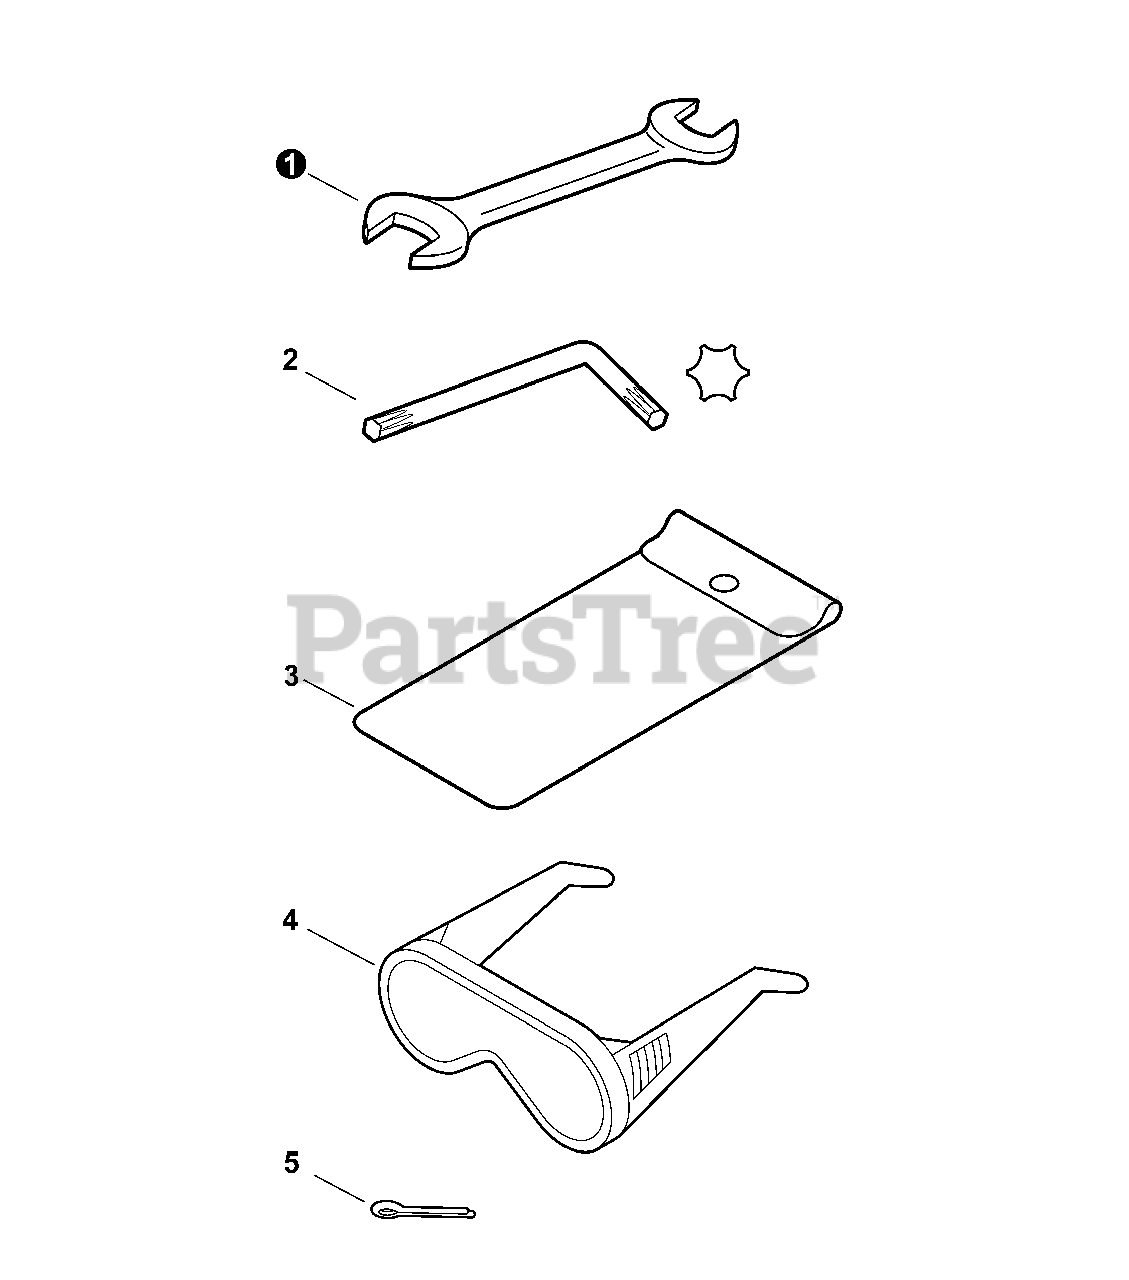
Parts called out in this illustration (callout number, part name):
1	SPANNER 8×10
2	WRENCH, T27 80×30
3	PIN - 2×22
4	GLASSES, SAFETY
5	PIN, COTTER 2×22
